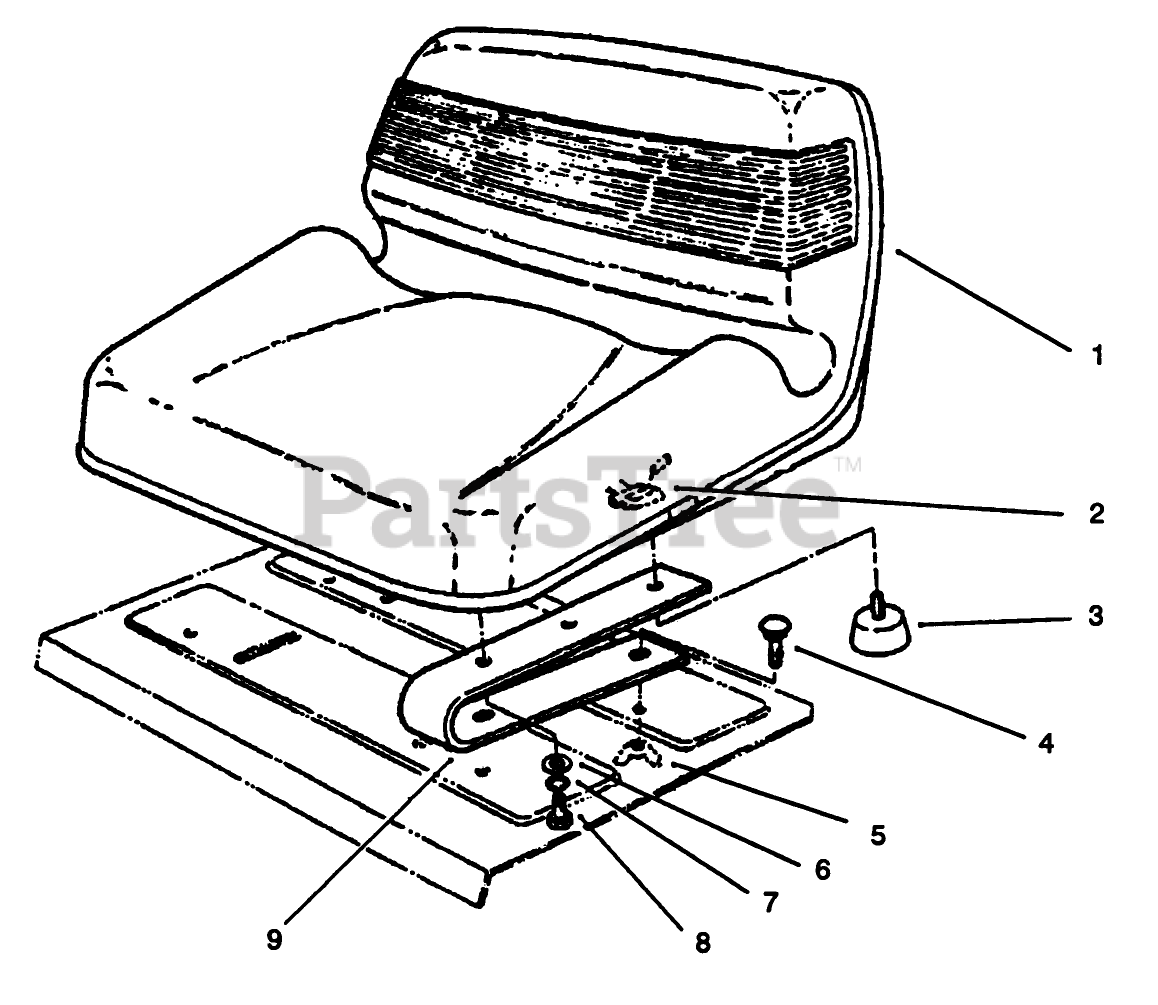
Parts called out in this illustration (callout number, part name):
1	Seat
2	SWITCH-SEAT
3	RUBBER BUMPER
4	SCREW-CARR
5	NUT-WING, LOCK
6	WASHER-PLAIN
7	WASHER-LOCK
8	SCREW-HH
9	Spring Seat
